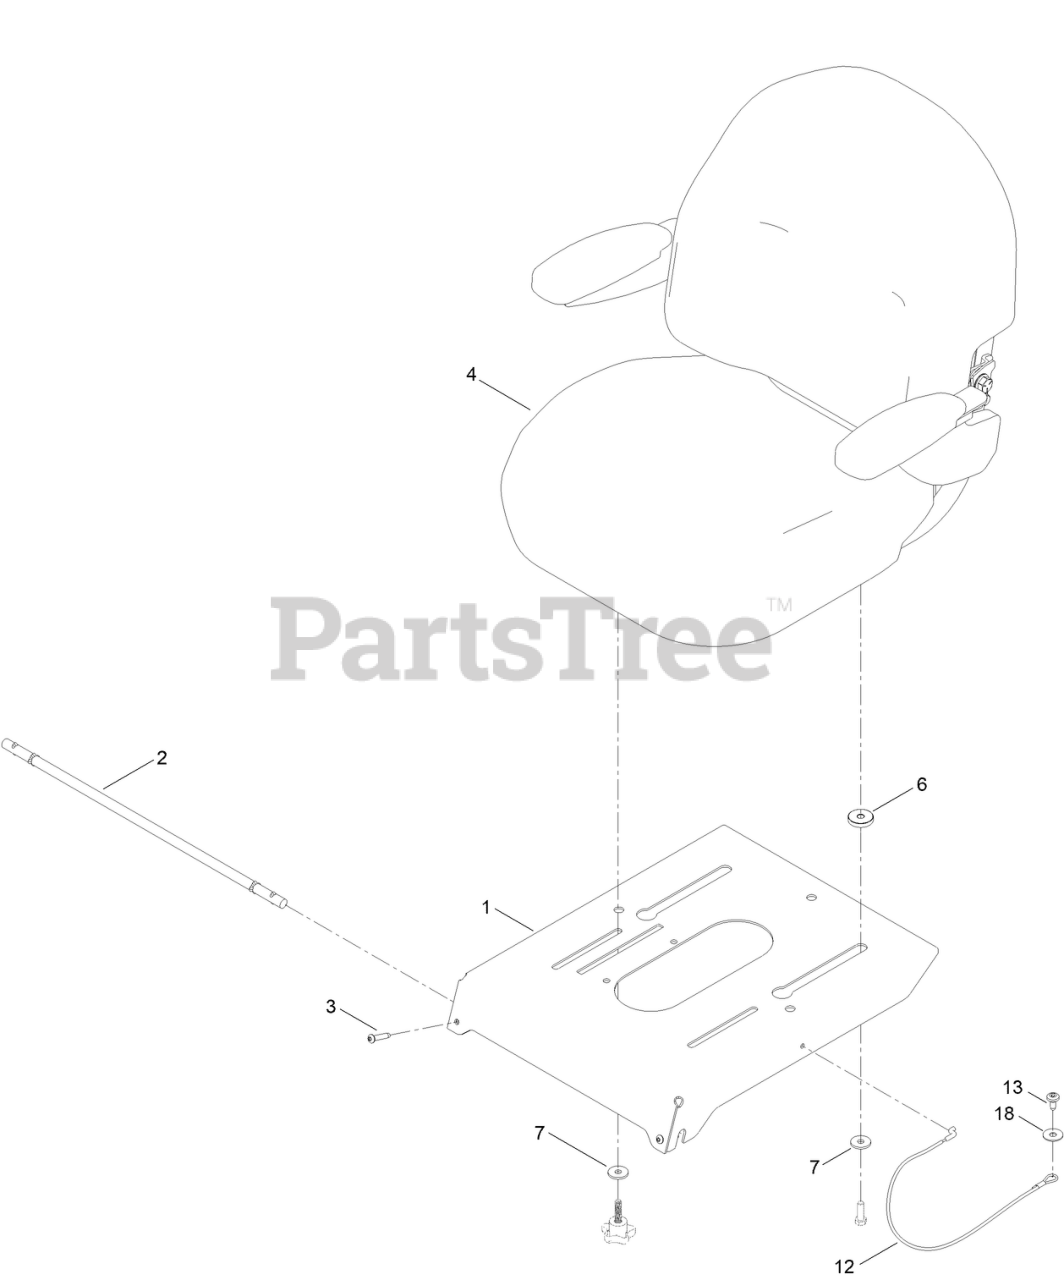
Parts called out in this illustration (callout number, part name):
1	PAN-SEAT, DELUXE
2	ROD-PIVOT
3	SCREW-TTH, THREAD ROLLING
4	SEAT ASM
6	SPACER-STEPPED
7	WASHER-FRICTION
12	CABLE-LANYARD
13	SCREW-SHOULDER
18	WASHER-FLAT
